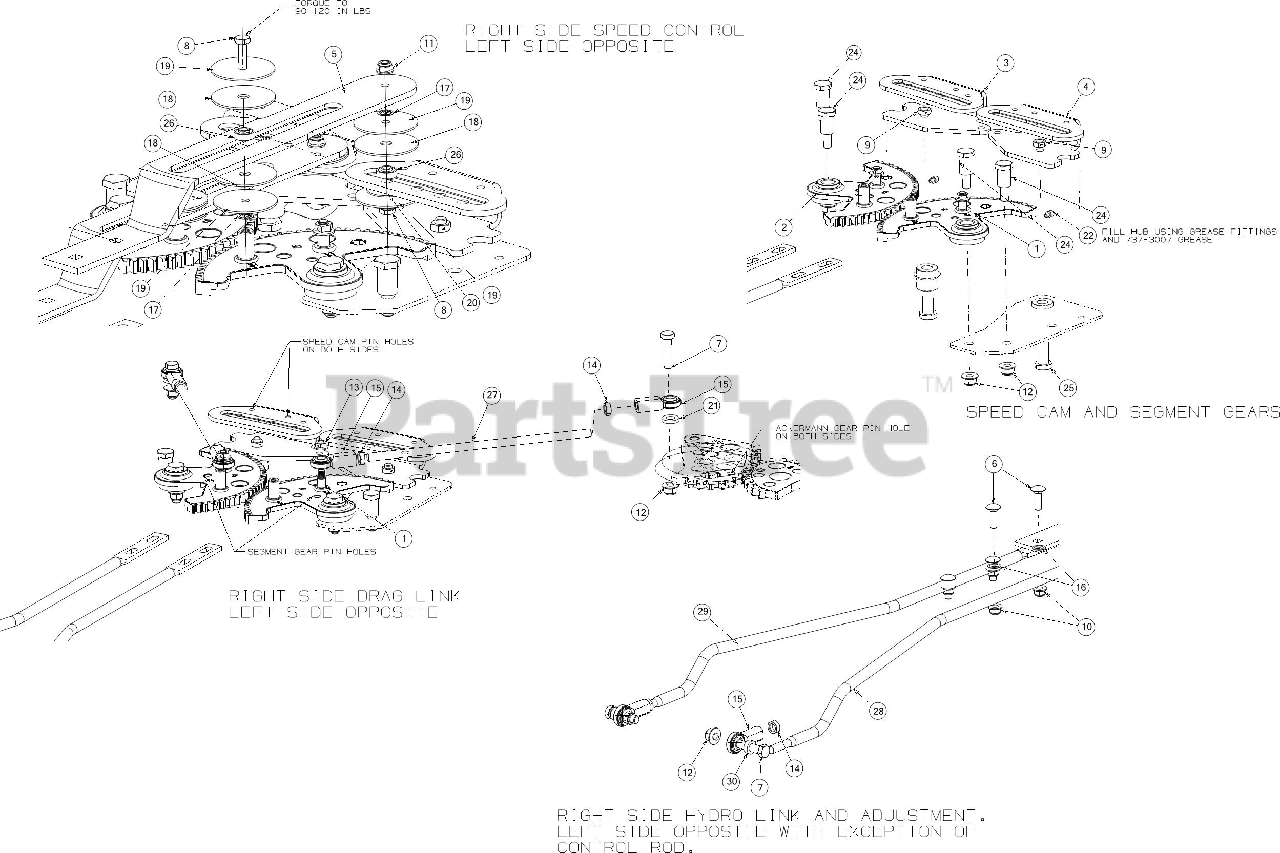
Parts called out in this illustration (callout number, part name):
1	STEERING GEAR ASSEMBLY (RH)
2	STEERING GEAR ASSEMBLY (LH)
3	SPEED CAM PLATE (LH)
4	SPEED CAM PLATE (RH)
5	CONTROL LINK
6	CARRIAGE BOLT 5/16-18 x 1.00
7	SCREW 3/8-16 x 1.50
8	SCREW 1/4-20X1.0 GR5
9	JAM LOCK NUT
10	FLANGE LOCK NUT 5/16-18
11	FLANGE LOCK NUT
13	FLANGE NUT
14	HEX JAM NUT 3/8X24
15	BALL JOINT (RH)
17	RETAINER-BOLT .25ID x .50OD
18	FLAT WASHER
19	FLAT WASHER
20	WASHER .355X1.25X.048THK
21	FLAT WASHER
22	GREASE FITTING
24	SHOULDER SCREW .625 x .875 x 3/18
25	SHOULDER SCREW .50
26	BALL BEARING .25 x .625 SPCL
27	STEERING DRAG LINK
28	HYDRO LINK ROD (RH)
29	HYDRO LINK ROD (LH)
30	SPACER-.380 ID X.625 OD x .227
